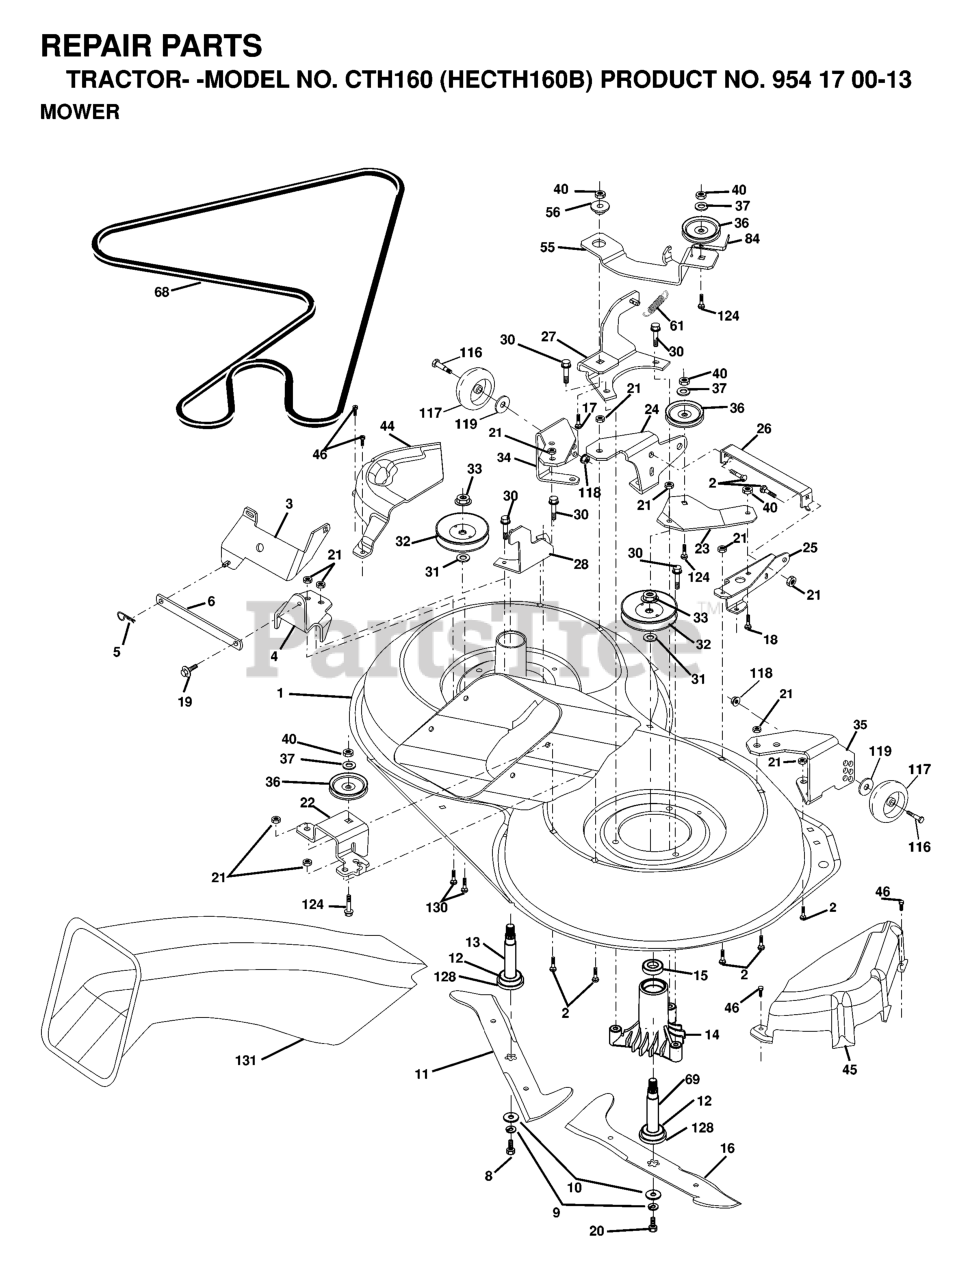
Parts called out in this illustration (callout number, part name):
1	MOWER HOUSING, DECK
2	RP BOLT 5/16-18 X3/4 ZN/YEL GR
5	RETAINER-SPRNG RB
6	BAR.SWAY.92.CRD
8	BLADE BOLT
9	LOCKWASHER
10	WASHER.BLADE
11	BLADE
12	BEARING.BALL.#6204.(MANDREL)
13	SHAFT ASM VENT
14	HOUSING.MANDREL.VENTED (MACHD)
16	BLADE.3-1.RH.CRD.92
17	BOLT.3/8-14X1.25
18	BOLT D
19	BOLT SHD 5/16-18
21	LOCKNUT
26	BRACE.SUPT.SUSP.FRT.CRD
30	SCREW THDROL ROLLING WASHER HD
31	WASHER
32	PULLEY, MANDREL
33	NUT
36	PULLEY.IDLER.4.25
37	WASHER
44	COVER.MANDREL.LH.92.CRD
45	COVER
46	SCREW.1/4-20X5/8
56	SPACER RETAINER
61	SPRING.TENSION.BELT
68	HEX-BELT 92 MOWER 105AA
69	SHAFT.ASM.W/LWR.BRG.RH.THREAD
84	KEEPER, BELT IDLER
116	BOLT, SHOULDER
117	WHEEL GAGE DONUT
118	LOCKNUT
119	WASHER.5/16.FLAT.STE.STD.
124	BOLT.3/8-16X1.50
128	WASHER FELT
130	BOLT.CARR.SQNK.5/16-18UNC.X3/4
131	CHUTE BAGGER
